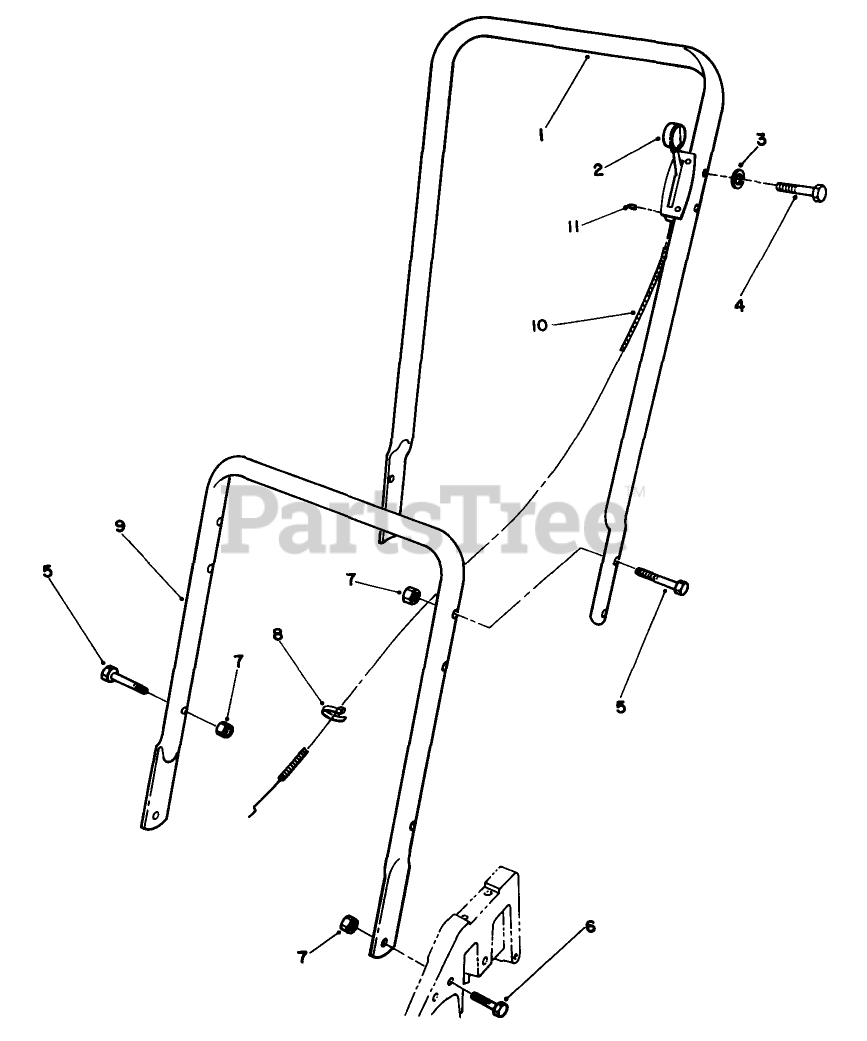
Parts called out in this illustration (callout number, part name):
1	Handle-Upper
2	Bracket Throttle
3	WASHER
4	SCREW-HH
5	SCREW-HH
6	SCREW-HH
7	NUT-LOCK, NI
8	TIE-CABLE
9	Handle-Lower
10	THROTTLE CABLE
11	E-RING
